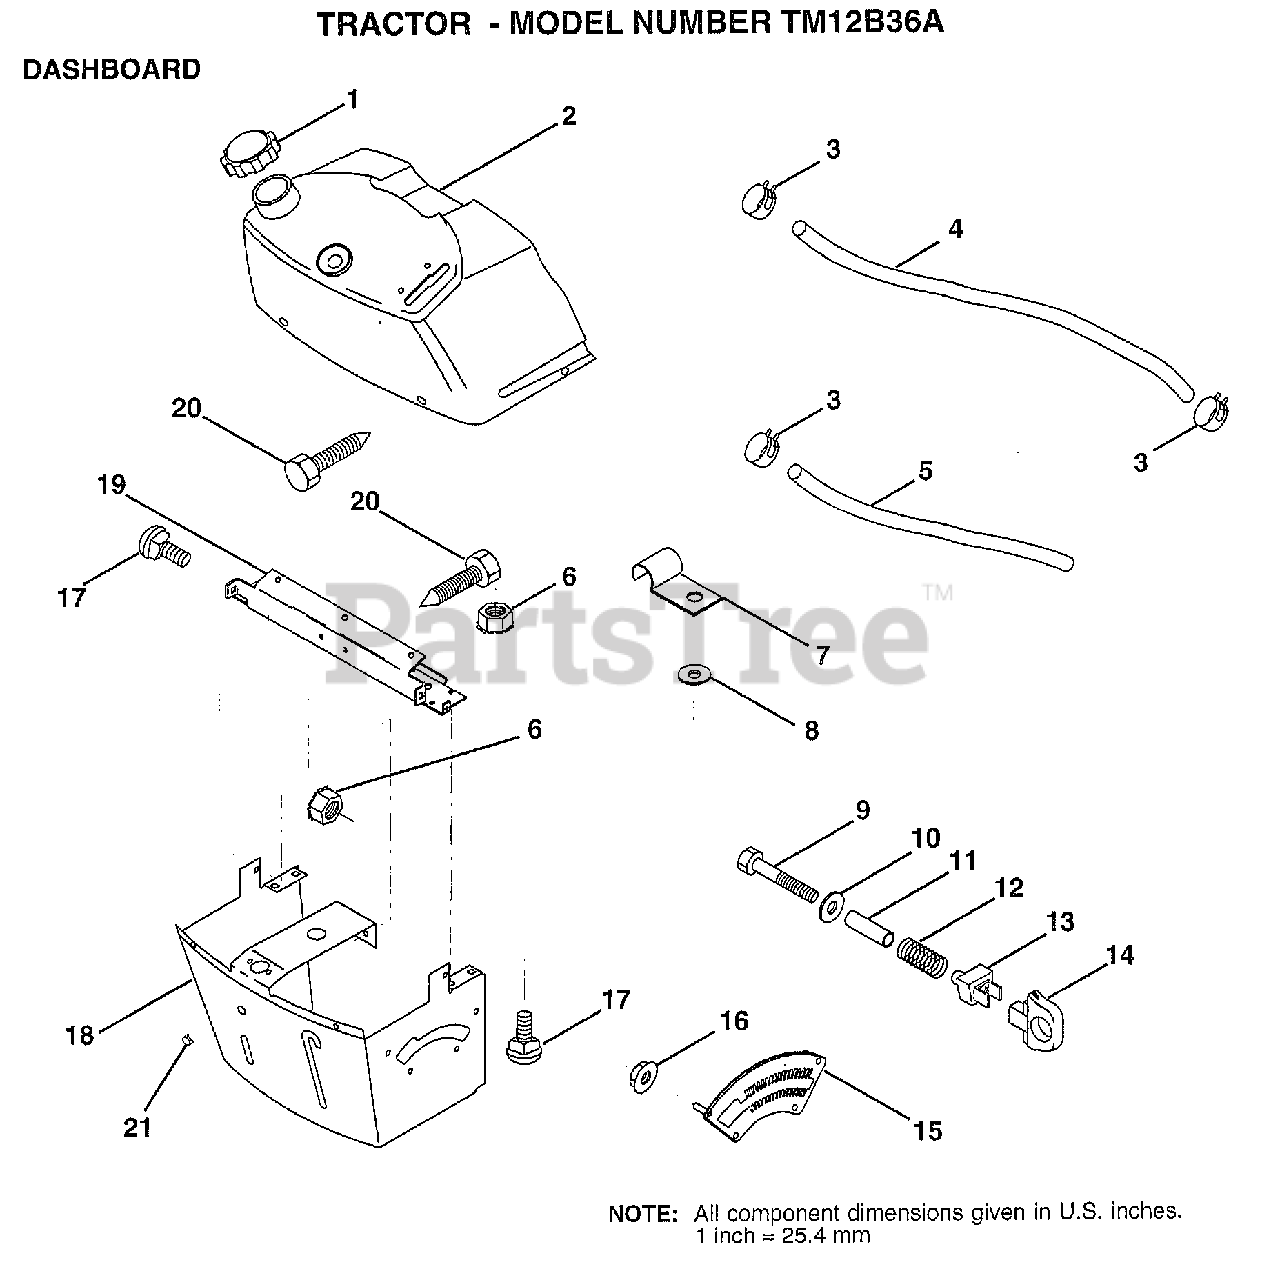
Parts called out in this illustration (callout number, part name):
1	CAP BLK FUEL LR
2	TANK.ASM.DASH.LR
3	HOSE CLAMP
5	FUEL LINE T
6	NUT HXKEP 1/4X20
7	CLIP T
8	WASHER PM
9	BOLT
11	SPACER SPLIT
12	SPRING M
13	"KNOB,HGT RETAINER"
14	KNOB
15	ADJUSTER QUAD
16	NUT
17	BOLT
18	SUPT ASSY DASH
19	CROSS BRACE
20	SCREW.1/4-20X1/2
21	PLUG DOME
